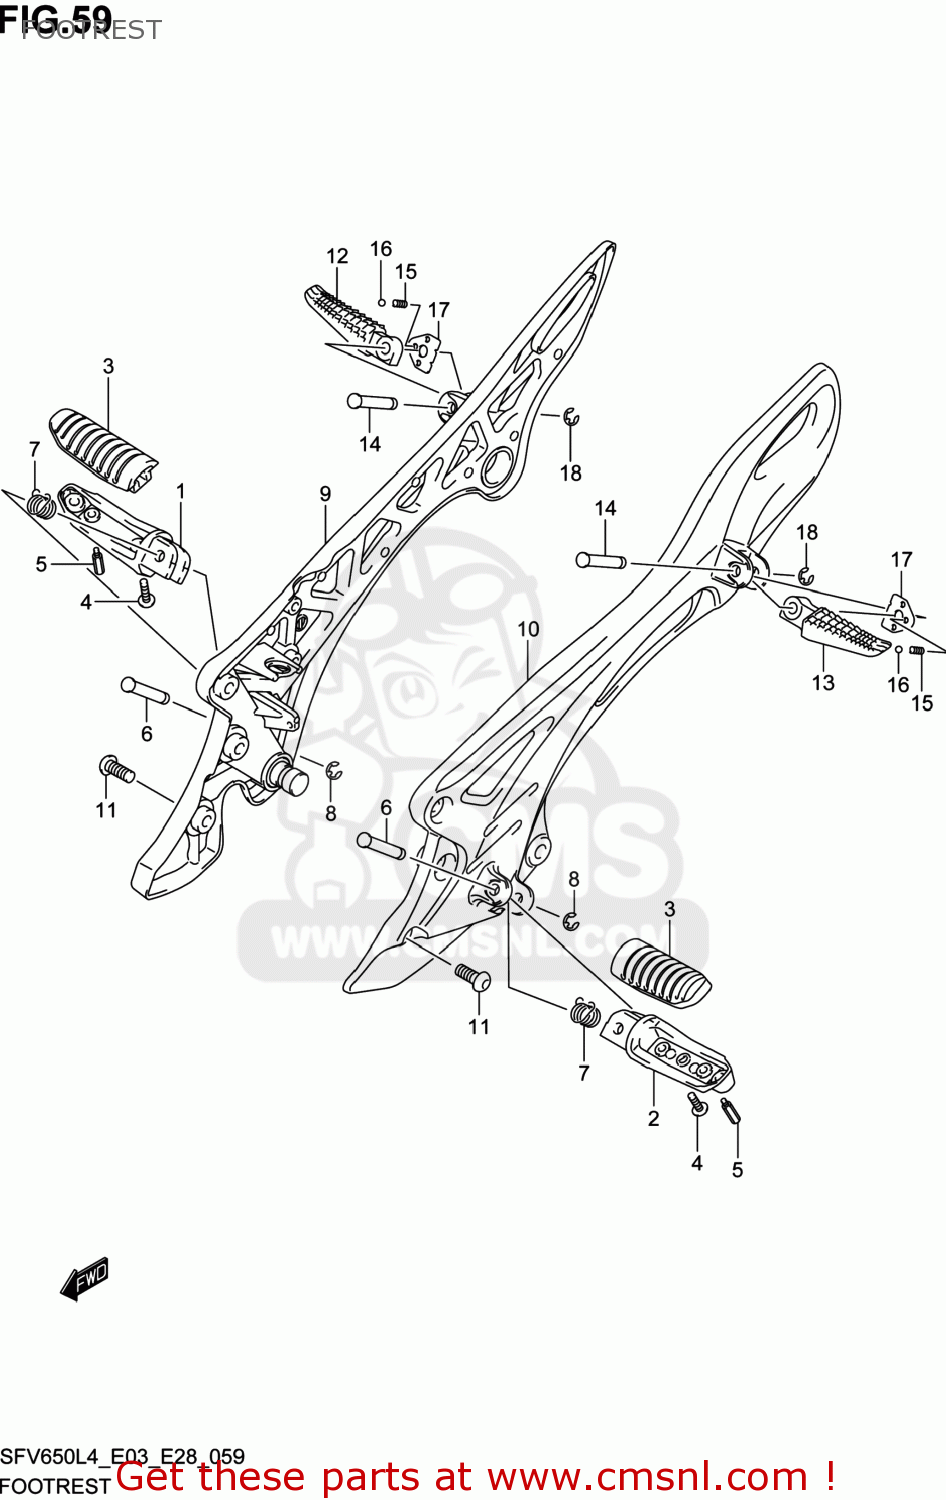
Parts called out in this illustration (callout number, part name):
1	BAR,FR FOOTREST,R
2	BAR,FR FOOTREST,L
3	RUBBER,FOOTREST BAR
4	SCREW
5	SENSOR,FOOTREST
6	PIN
7	SPRING
8	E RING
9	BRACKET,FOOTREST,R
10	BRACKET,FOOTREST,L
11	BOLT(8X23)
12	BAR,PILLION FOOTREST,R
13	BAR,PILLION FOOTREST,L
14	PIN
15	SPRING
16	BALL
17	PLATE,PILLION FOOTREST
18	E RING
